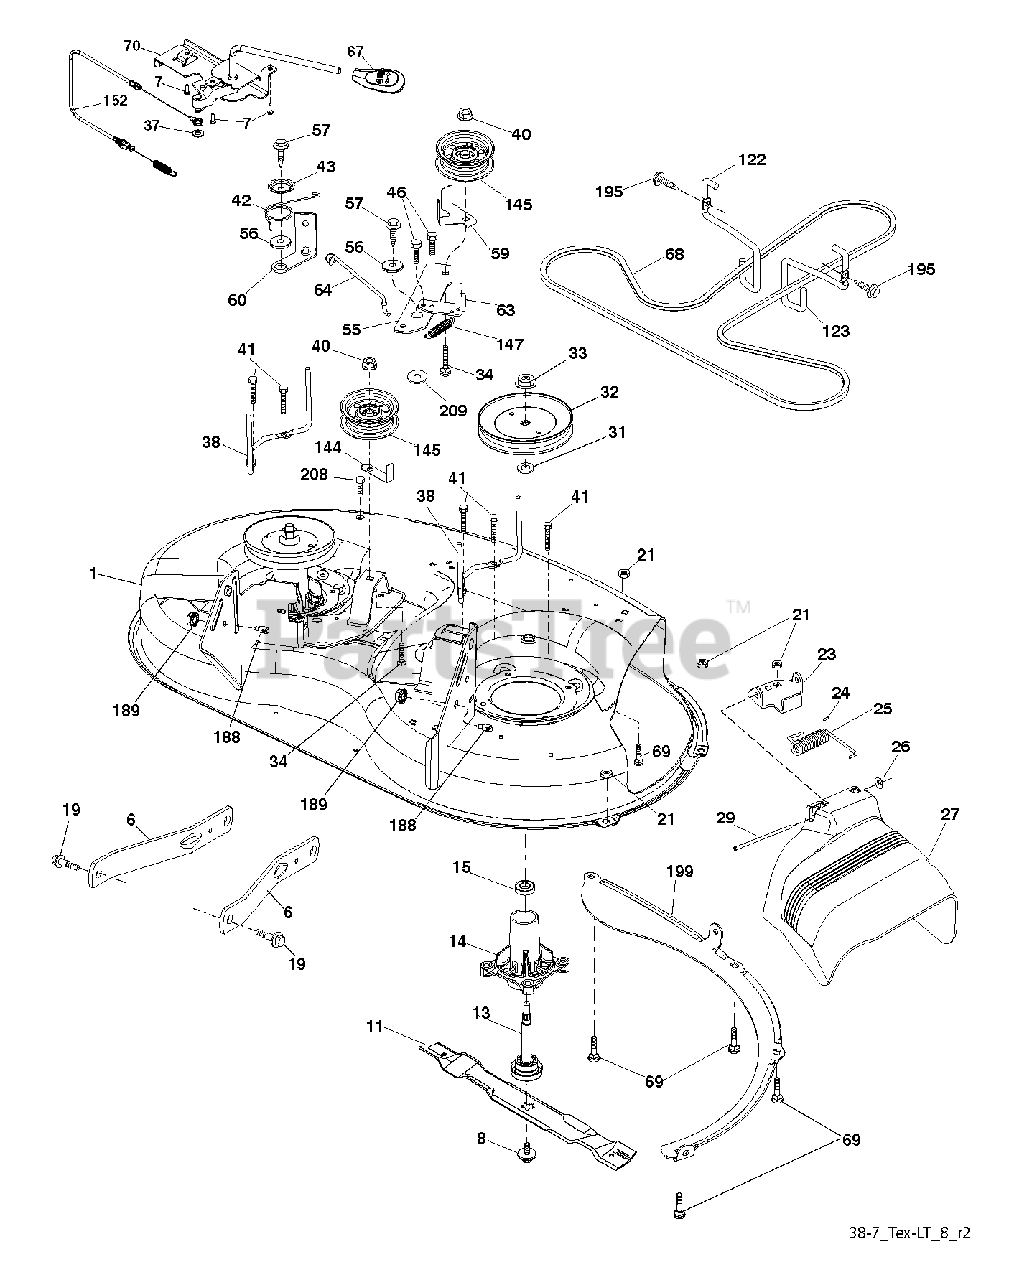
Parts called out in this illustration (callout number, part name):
6	ARM.SUSPENSION.MOWER.R
7	SCREW.#10 X 0.750.BOS (2 2)
8	BOLT.WASHER.ASM.7/16-2
11	BLADE 38" PREMIUM
13	SHAFT.ASM.MDRL.N/GREASE.38
14	HOUSING.MANDREL.4PT.
19	BOLT.SHOULDER
21	LOCKNUT
23	BRKT.DEFLECTOR.38"2005+
24	CAP-SLEEVE LT
25	SPRING.TORSION.DEFLECT
26	NUT PUSH M
27	SHIELD, DEFLECTOR
29	ROD.HINGE
31	WASHER.SPACER.MANDREL
32	PULLEY.MANDREL.5.0.PD.38"
33	NUT.FLANGE.LOCK.TOP
34	BOLT.3/8-16X1.50
38	KEEPER BELT LH MANDREL
40	NUT LOCK FLG 3/8-16 UNC
41	Hex Washer Head Bolt, .313-18 X 1.19
42	SPRING.TORSION.BRAKE
43	SRPING.TORSION.RETAINE
46	SCREW.1/4-20X5/8
55	IDLER.ARM
56	SPACER.RETAINER
57	SCREW 3/8-16X1
59	GUARD, BELT
60	ARM BRAKE MOWER RH 38"
63	ARM BRAKE MOWER RH
64	LINK BRAKE
67	HANDLE.CLUTCH.CABLE.LT
68	Drive Belt, 38"
69	BOLT
70	CLUTCH.ASM.MANUAL.LT.TEX
122	KEEPER BELT ENGINE LH
123	KEEPER BELT RH
144	KEEPER BELT
145	PULLEY.IDLER.48"PRIMARY
147	SPRING RETURN
152	CABLE.CLUTCH.MANUAL.
188	STUD.FASTNER.W/ANTI-ROTATE
189	NUT LOCK HEX FLANGE 5/16-18
195	SCREW, 3/8-16X3/4
199	BAFFLE.VORTEX.FRONT.38"
208	SCREW 3/8-16X1/2
209	WASHER 12/32X2X10GA
